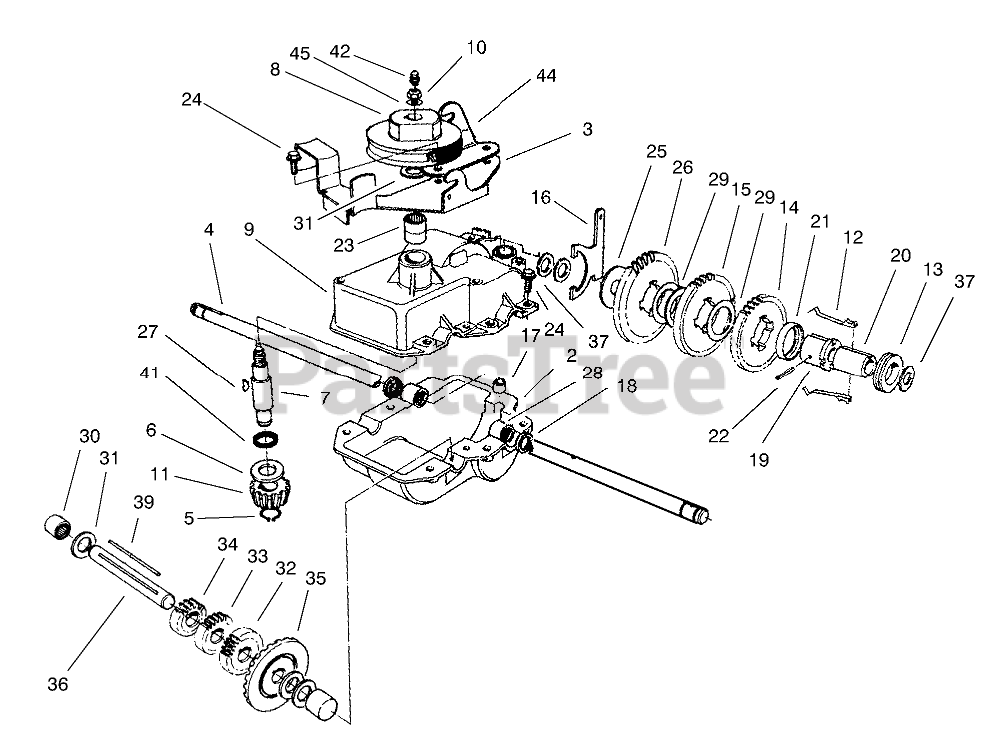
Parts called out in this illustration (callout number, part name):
2	CASE-GEAR, LOWER
3	BRACKET-GUIDE, BELT
4	SHAFT-OUTPUT
5	RING-RETAINING
6	WASHER-THRUST
7	Shaft-Input
8	PULLEY
9	CASE-GEAR, UPPER
10	NUT-HEX
11	PINION-BEVEL
12	KEY-SHIFT
13	COLLAR-SHIFT
14	GEAR-38T
15	GEAR-42T
16	YOKE-SHIFT
17	BUSHING-YOKE
18	SEAL-OIL
19	SLEEVE-GEAR
20	SLEEVE
21	RETAINER-KEY
22	PIN-GROOVE
23	BEARING-NEEDLE
24	SCREW-HWHTF
25	WASHER
27	KEY-WOODRUFF
28	BEARING-ROLLER
29	WASHER
30	BEARING-NEEDLE, CLOSED
31	WASHER-THRUST
32	GEAR-18T
33	GEAR-14T
34	GEAR-12T
35	GEAR-BEVEL
36	SHAFT-INTERMEDIATE
37	WASHER-PLAIN
42	FITTING-GREASE, ZERK
44	BRACKET-ENGAGE, TRACTION
45	WASHER-FLAT
